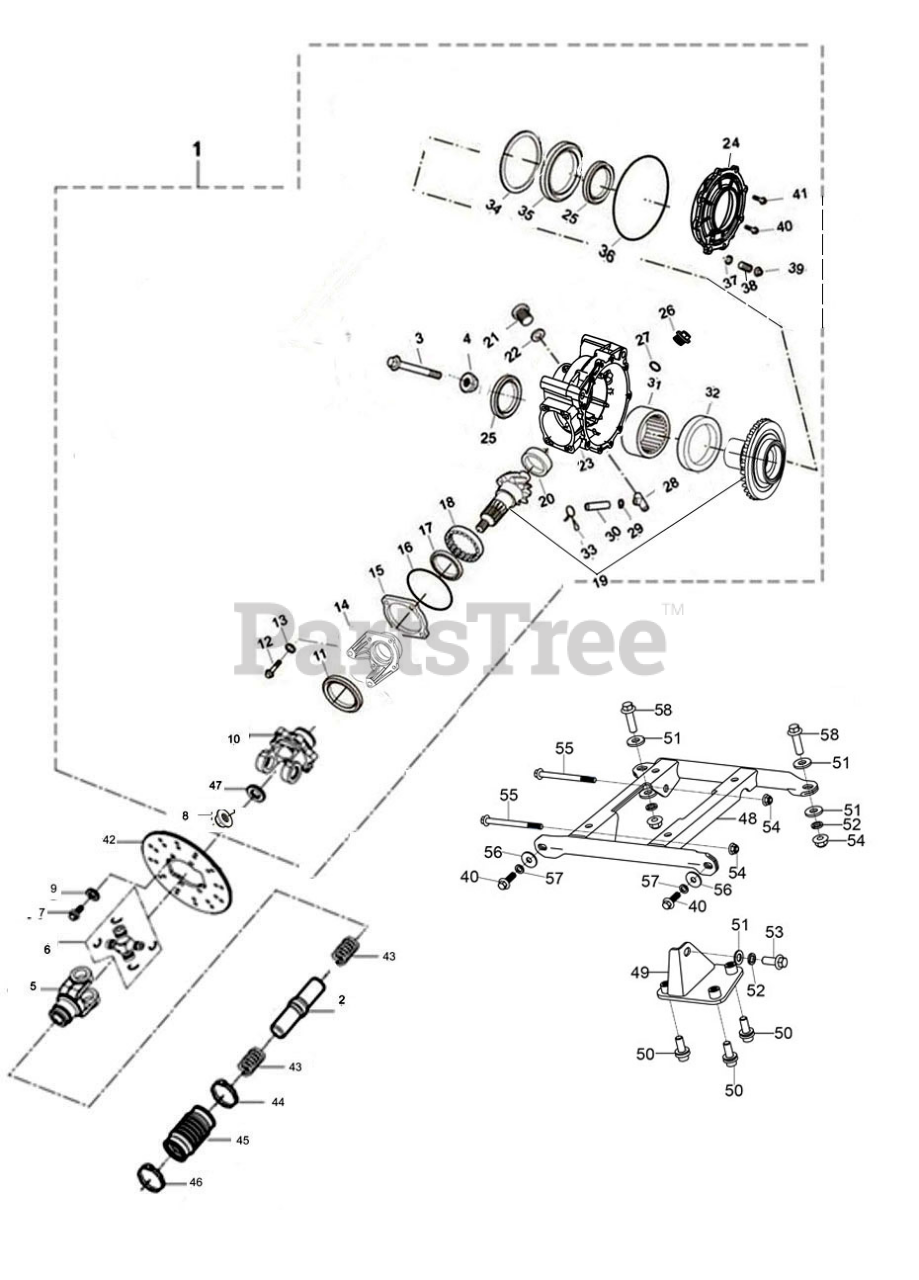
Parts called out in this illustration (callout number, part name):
1	DIFFERENTIAL (REAR)
2	SHAFT (REAR) (RH)
3	HEX FLANGE BOLT M10 x 1.25 x 120
4	NUT M10X1.25
5	U-JOINT YOKE (SPLINED)
7	HEXAGON FLANGE BOLT M8X20
8	LOCK NUT M12x1.25
9	SPRING WASHER-8
10	U JOINT YOKE
12	HEXAGON FLANGE BOLTS M8X35
14	CALIPER MOUNT CASE
16	O-RING 3.1 x 63.8
18	CLAMP BUSHING
19	DRIVEN GEAR ASSEMBLY
20	NEEDLE BEARING 22 x 30 x 13
21	FLANGE BOLT M10X1.25X16
22	O-RING 1.5 x 13
23	DIFF CASE (REAR)
24	DIFF COVER-REAR
25	OUTPUT OIL SEAL 70 x 90 x 9
26	DRAIN PLUG
27	O-RING 18 X 2.65
28	DIFF AIR FITTING (REAR)
29	SPRING CLAMP C
30	AIR VENT LINE
31	NEEDLE BEARING 55 x 67 x 20
32	ADJUSTMENT WASHER 55.2 x 66.8 x 1.7
33	CLAMP-10MM
34	ADJUSTMENT WASHER 86 x 100 x 0.1
35	BEARING 16017
36	O-RING 1.8 X 150
37	COPPER WASHER 8.2 x 1
38	SET SCREW M8 x 45
39	HEXAGON FLANGE NUT M8
40	FLANGE BOLT M8X25
41	HEX FLANGE BOLT M10X1.25X20
42	BRAKE DISC
43	COMPRESSION SPRING
44	NARROW BAND CLAMP
45	NARROW BAND CLAMP
46	NARROW BAND CLAMP
48	DIFF BRACKET (UPPER)
49	DIFF BRACKET (LOWER)
50	HEX BOLT & WASHER ASSEMBLY
52	SPRING WASHER
53	HEXAGON FLANGE BOLT M10X30
54	LOCK NUT M10X1.25
55	HEX FLG BOLT 10 x 1.25 x 125
56	WASHER - FLAT 10X28X2
57	SPRING WASHER-8
58	HEX BOLT-FLG HEAD 10x1.25x35
